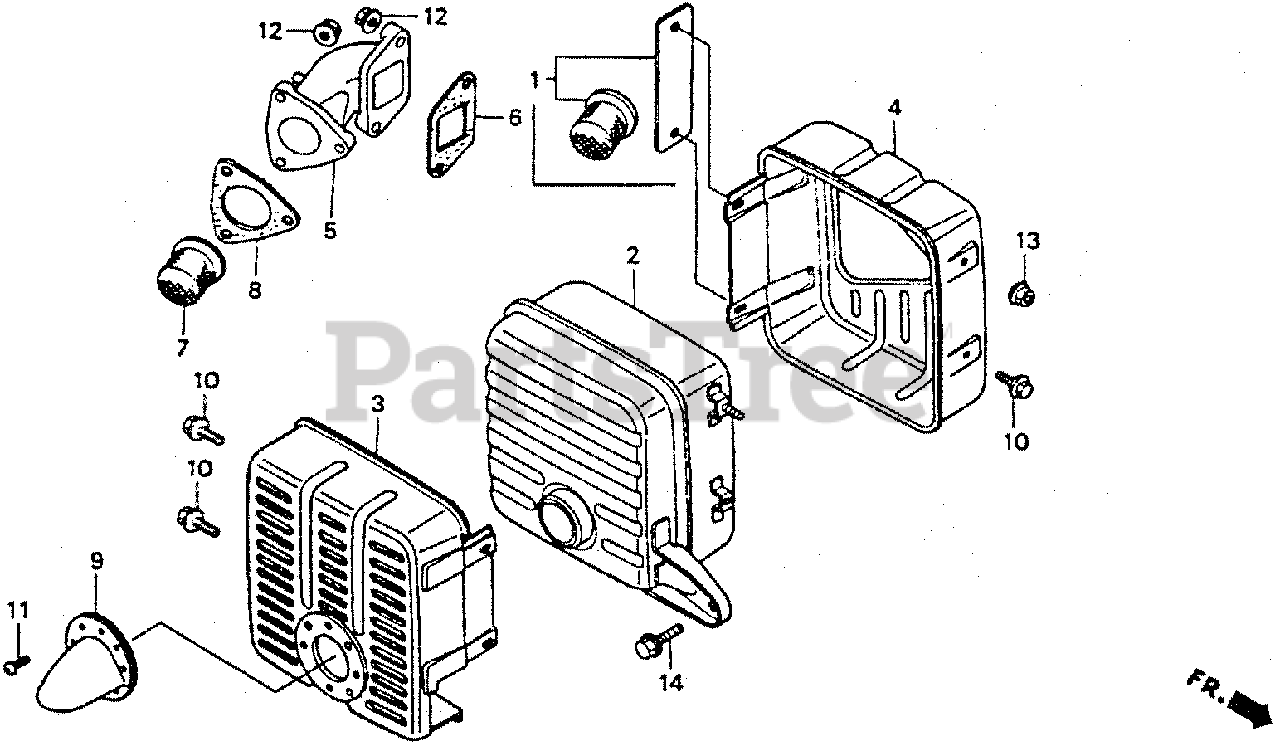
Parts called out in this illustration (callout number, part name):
1	ARRESTER KIT, SPARK
2	MUFFLER
3	PROTECTOR A, MUFFLER
4	PROTECTOR B, MUFFLER
5	PIPE, EX.
6	GASKET, EX. PIPE (NON-ASBESTOS)
8	GASKET, MUFFLER (NON-ASBESTOS)
9	DEFLECTOR, MUFFLER
10	BOLT, FLANGE (5X8)
11	SCREW, PAN (5X8)
12	NUT, FLANGE (8MM)
13	NUT, FLANGE (8MM)
14	BOLT, FLANGE (8X20)
